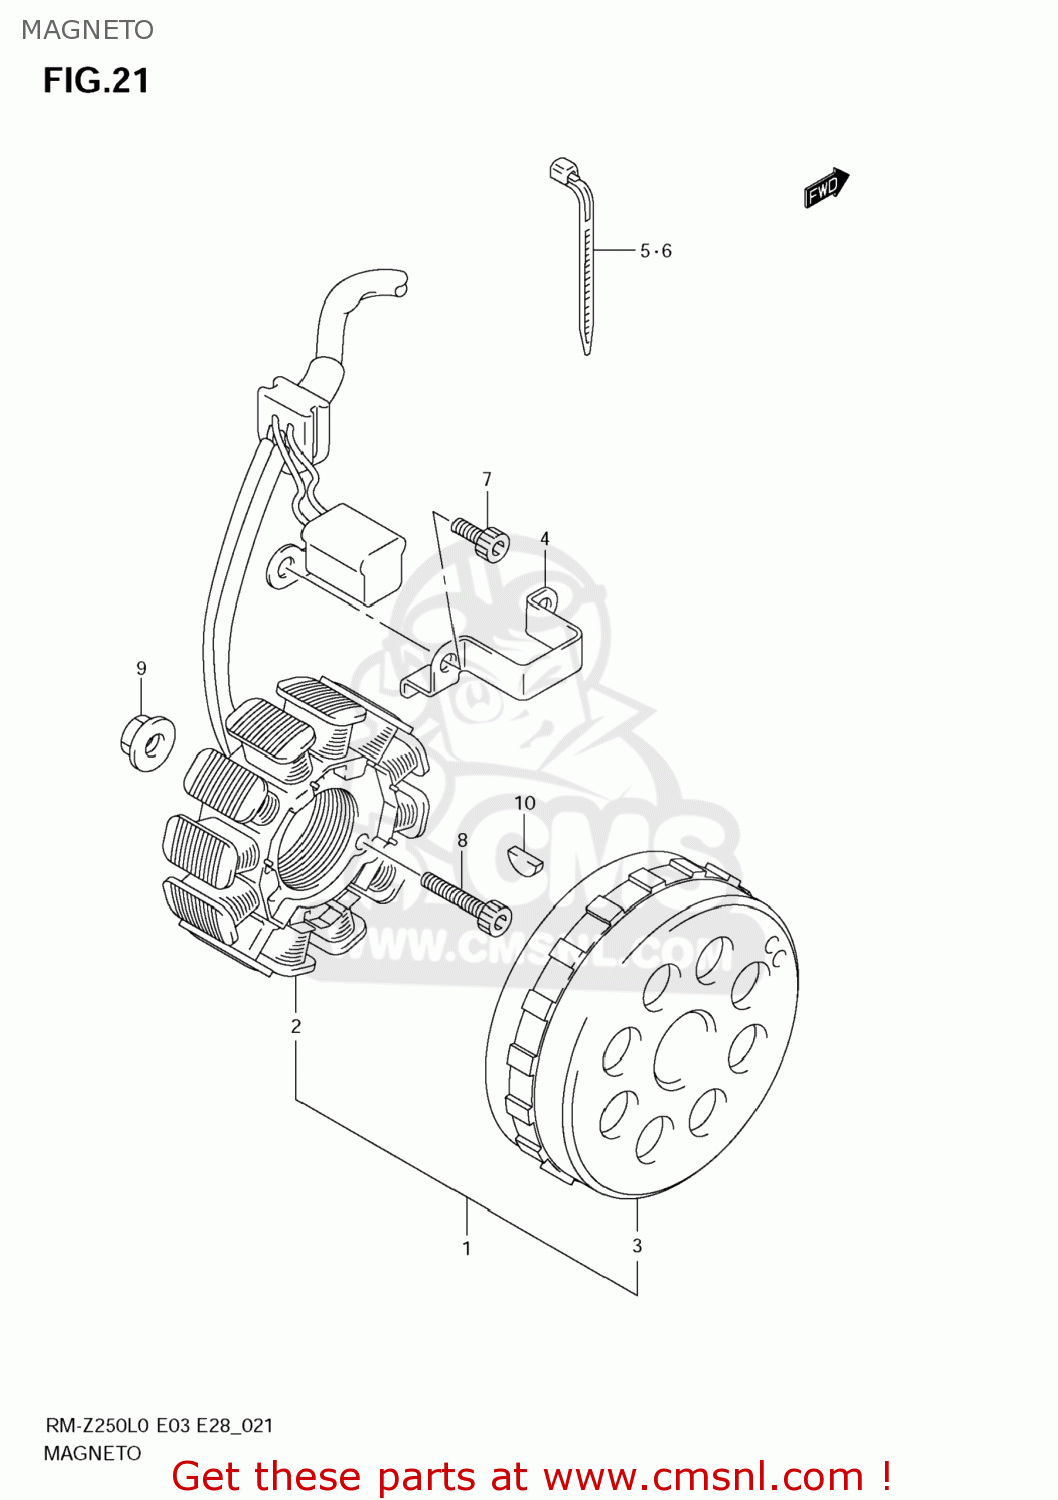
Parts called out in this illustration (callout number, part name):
1	MAGNETO ASSY
2	STATOR ASSY
3	ROTOR ASSY
4	CLAMP,MAGNETO LEAD
5	CLAMP(L:125)
6	CLAMP(L:235)
7	BOLT
8	BOLT
9	NUT
10	KEY
